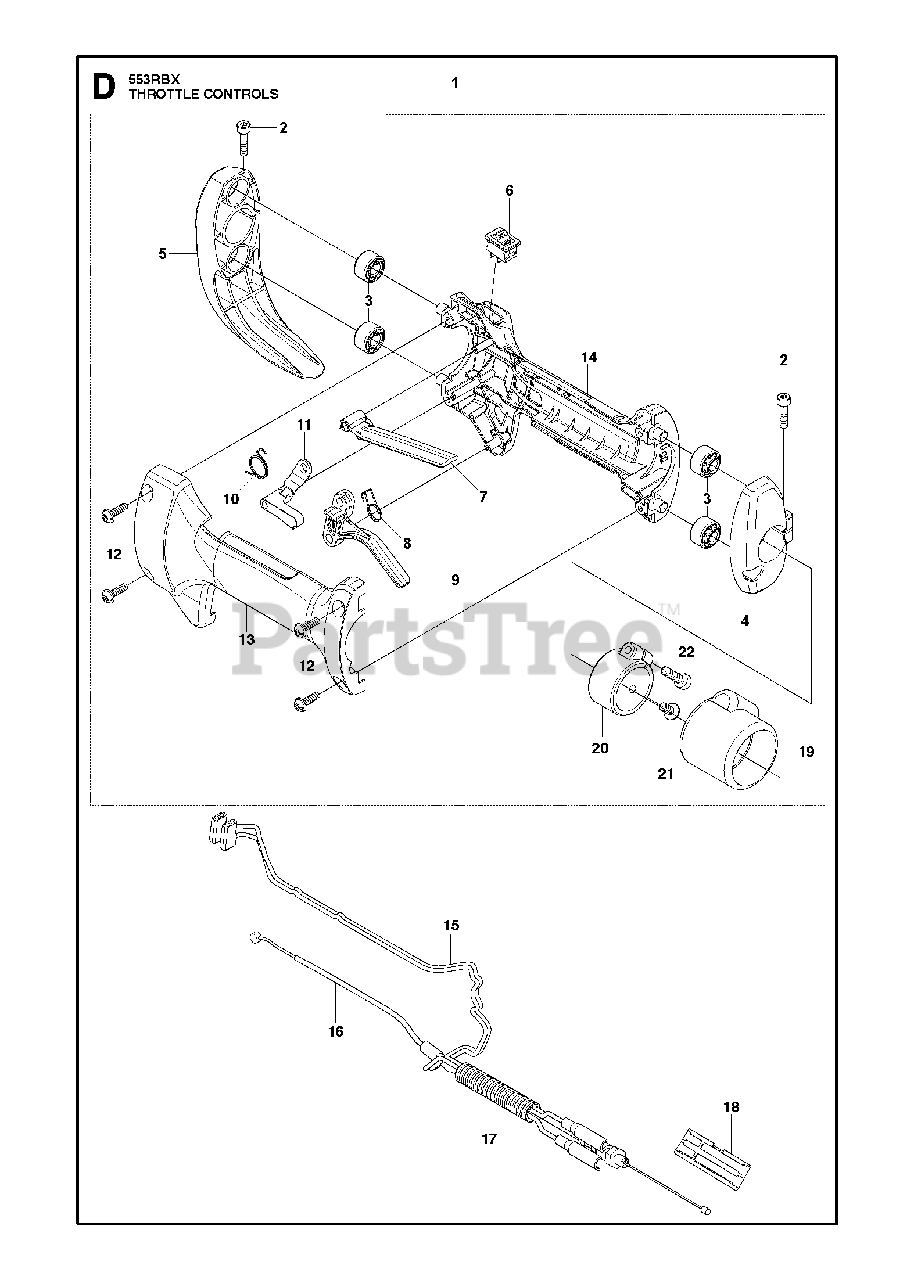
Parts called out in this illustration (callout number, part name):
2	RP BOLT TORX M5XL20 T27
6	SWITCH
10	SPRING
12	SCREW
22	BOLT TORX
